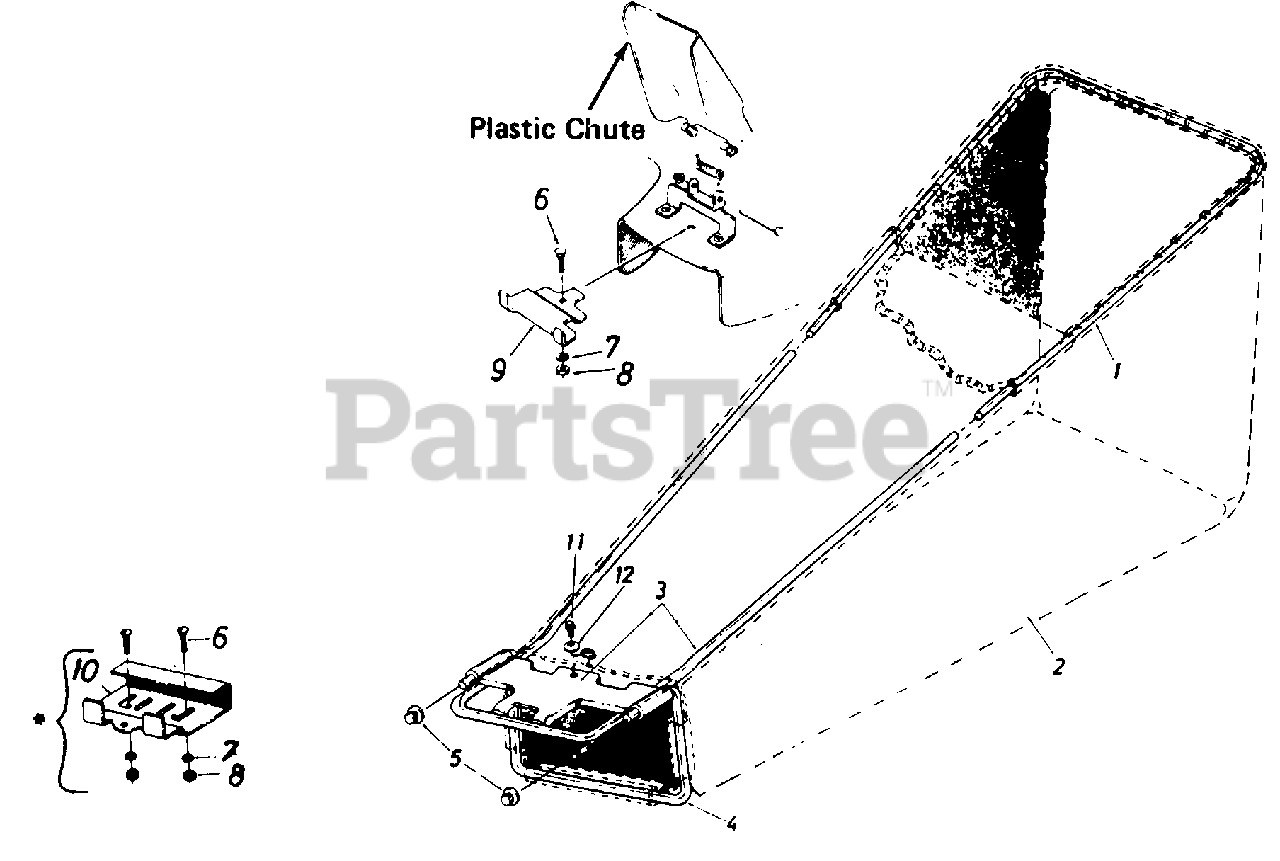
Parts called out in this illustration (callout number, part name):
1	FRAME-UPPER
2	BAG-GRASS
3	FRAME-LOWER
4	ROD-FRAME-LWR
5	NUT-SPEED
6	BOLT-CARRIAGE 1/4-20 X .50
7	LOCK WASHER 1/4 DIA
8	NUT-HEX 1/4-20
9	PLATE-ADAPTER
10	PLATE-ADAPTER
11	SCREW-HEX WASH SF TAPP
12	WASHER-SPRING BELL
